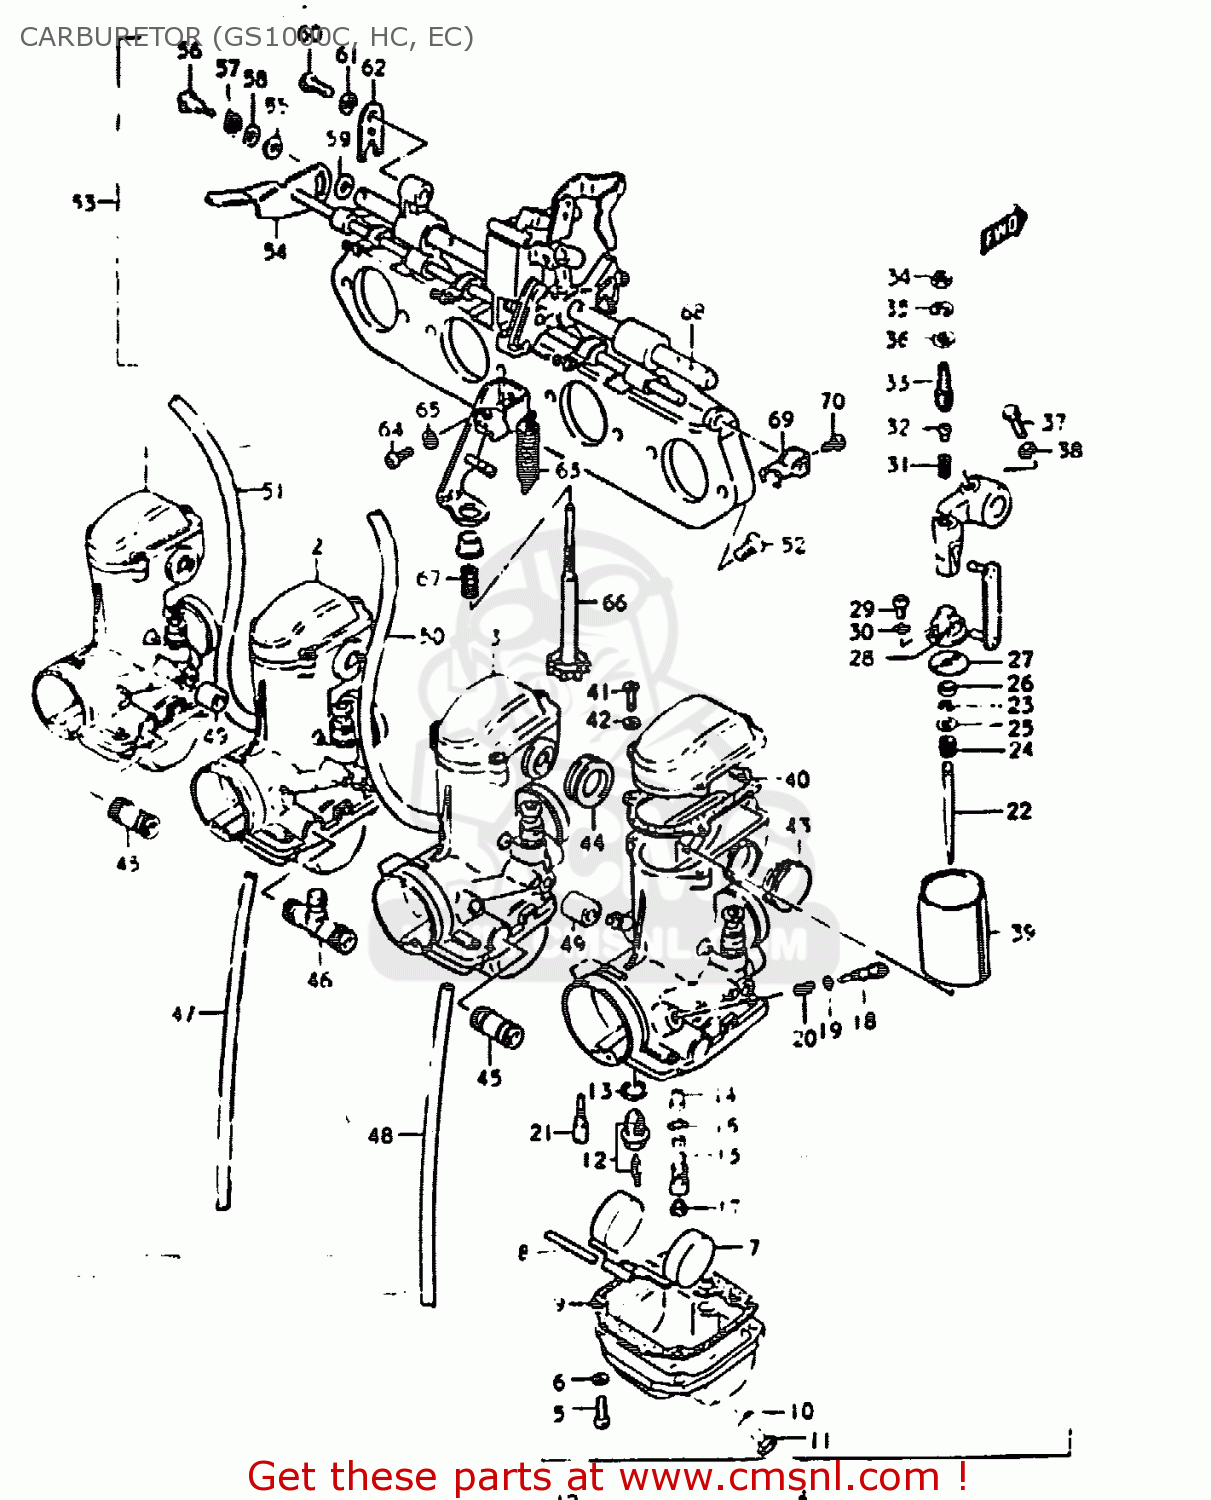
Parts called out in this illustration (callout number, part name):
1	CARBURETOR ASSY, NO.1
2	CARBURETOR ASSY, NO.2
3	CARBURETOR ASSY, NO.3
4	CARBURETOR ASSY, NO.4
5	SCREW
6	LOCK WASHER
7	FLOAT
8	PIN,FLOAT
9	GASKET,FLOAT CHAMBER (NAS)
10	O RING
11	SCREW
12	VALVE ASSEMBLY,NEEDLE
13	GASKET,VALVE SEAT (NAS)
14	JET, NEEDLE
15	PIPE,BLEEDER
16	O RING
17	JET,MAIN(95)
18	SCREW,PILOT AIR
19	O RING
20	SPRING
21	JET, PILOT
22	NEEDLE,JET
23	CLIP
24	SPRING
25	WASHER,JET NEEDLE
26	RING
27	PLATE,THROTTLE VALVE
28	CONNECTOR
29	SCREW
30	LOCK WASHER
31	SPRING
32	PIN,CARBURETOR
33	SCREW
34	NUT
35	LOCK WASHER
36	WASHER
37	BOLT
38	LOCK WASHER
39	VALVE,THROTTLE
40	GASKET (NAS)
41	SCREW
42	LOCK WASHER
43	PIPE,DELIVERY
44	SEAL
45	NIPPLE
46	NIPPLE
47	HOSE
48	HOSE
49	HOSE
50	HOSE 4.5X8X390
51	HOSE 4.5X8X390
52	SCREW
53	CARBURETOR ASSEMBLY
54	SHAFT,STARTER
55	WASHER
56	SCREW,STARTER LEVER
57	SPRING
58	WASHER,STARTER SHAFT
59	WASHER,STARTER SHAFT
60	SCREW
61	LOCK WASHER
62	GASKET
63	SPRING
64	SCREW
65	LOCK WASHER
66	ADJUSTER
67	SPRING,THROTTLE SCREW
68	SHAFT ASSEMBLY
69	LEVER, STARTER
70	SCREW
